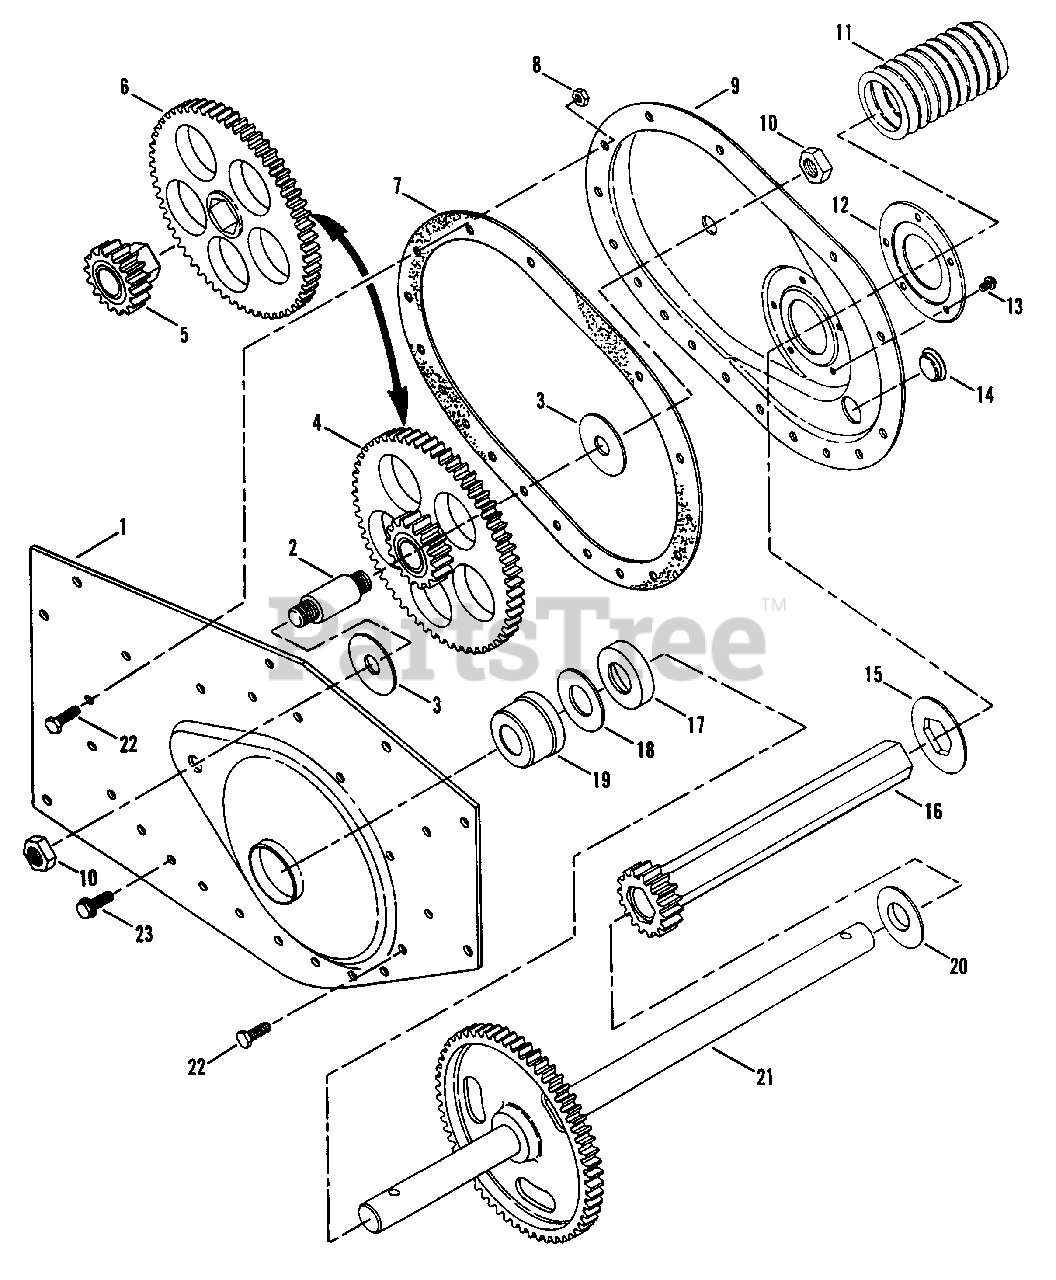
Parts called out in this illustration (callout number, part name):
1	FRAME, Left Side
2	SHAFT, Hex Gear
3	WASHER, Thrust
4	ASSEMBLY, Gear Cluster
5	ASSEMBLY, Hex Gear (15 Tooth)
6	GEAR (64 Tooth)
8	NUT, 1/4-28 Hex Top-Lock
10	NUT, 1/2-20 Hex Center-Lock
11	SEAL, Short
12	RETAINER, Boot
13	SCREW, #10-32 x 1/4" Self-Tapping
14	PLUG, 3/4"
15	WASHER, Plastic
16	ASSEMBLY, Tube Drive
18	WASHER, Thrust
19	BEARING, Axle .76" ID x 1.626"/1.75" OD x 1.06" Long
20	WASHER, Thrust
21	WELDMENT, Axle & Gear
22	SCREW, 1/4-28 x 1/2" Hex Head Cap, Grade 5
23	SCREW, 1/4-20 x 1/2" Self-Tapping
